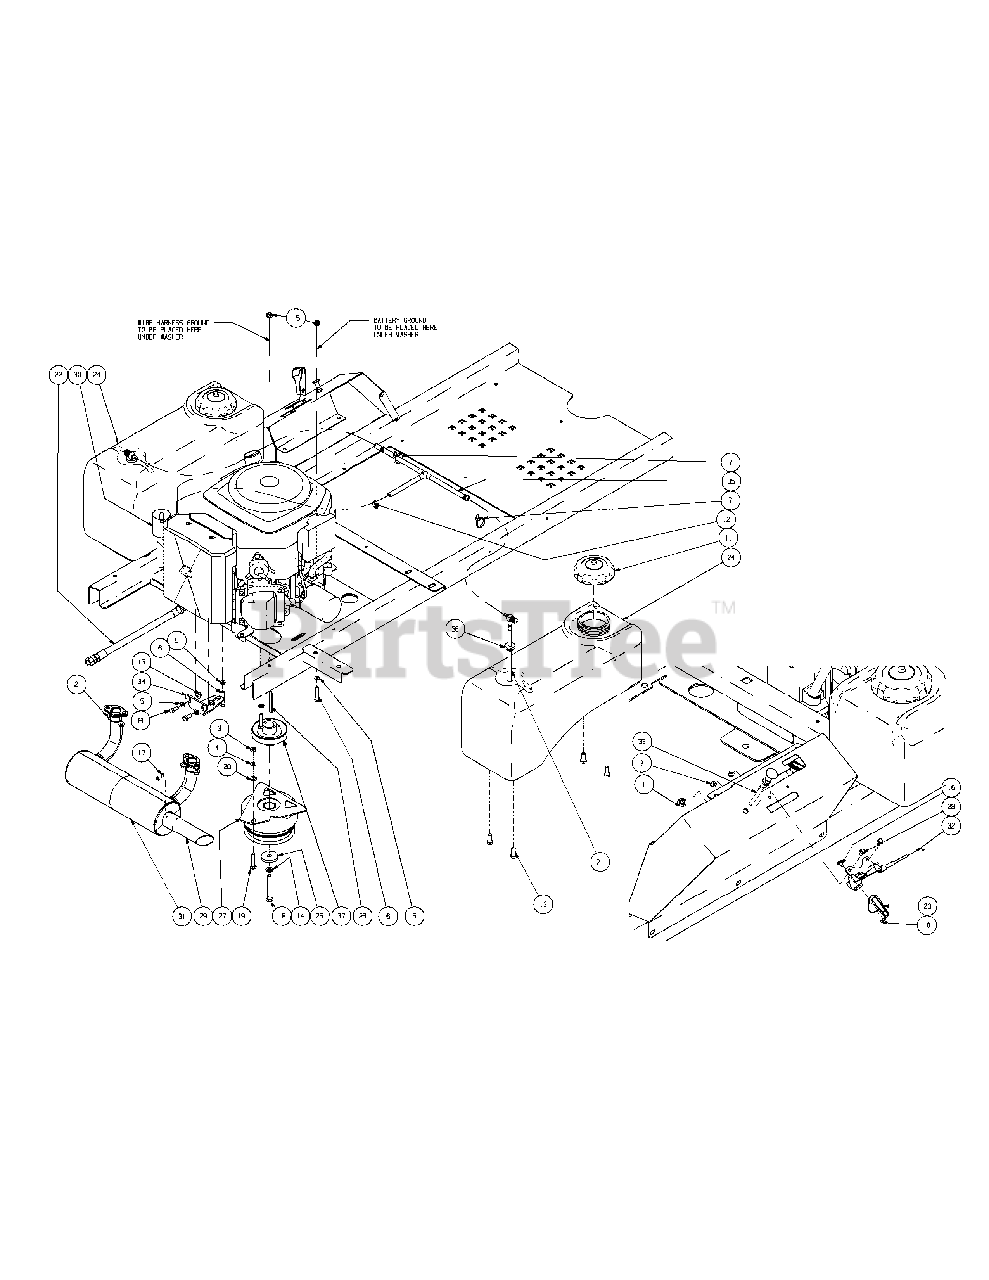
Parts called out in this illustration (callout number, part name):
1	Jam Nut, 3/8-24
2	Nut, M8-1.25, Hex Flange
3	Hex Nut, 5/16-18
4	Lock Washer, 5/16
5	Flat Washer, 5/16
6	HHCS, 5/16-18, 1-1/2
7	Cable Tie, 3/16 x .05 x 7.4
8	Hex Cap Screw, 5/16-18 x .75
9	Lock Nut, Nylon Insert, 10-32
10	Nut, w/ Star Washer
12	Hose Clamp, SAE #4: 1/4-5/8, SS
13	HHCS, 3/8-16 x .500, Flange Whiz
14	Lock Washer, 7/16
15	Lock Nut, Hex Flange, 5/16-18
16	Machine Screw, 8-32 x .375
17	Screw, 8-32 x .375, Hex Washer
18	Hex Cap Screw, 7/16-20 x 3.0
19	Carriage Bolt, 5/16-18 x 1.75
20	Washer, 3/8 x .738 x .063
21	Fuel Pickup Fitting
22	Oil Drain Extension Hose
23	Throttle Control Knob
24	Fuel Tank
25	Flat Washer, 7/16 ID x 1.75 OD x .250
26	Key, 1/4 x 1/4 x 2.75
27	Ogura DX11 Electric Clutch
28	Screw, #10-32 x 0.500
29	Exhaust Pipe
30	20HP Kohler Engine
31	Muffler, Silexsys
32	Throttle Control Cable
33	Choke Cable
35	Fuel Hose Assembly includes:
35	Hose, 1/4" Fuel Line (70 inches)
35	Clamp, Union
35	Tee Fitting, Fuel
36	Fuel Tank Groment
37	Transmission Drive Pulley
